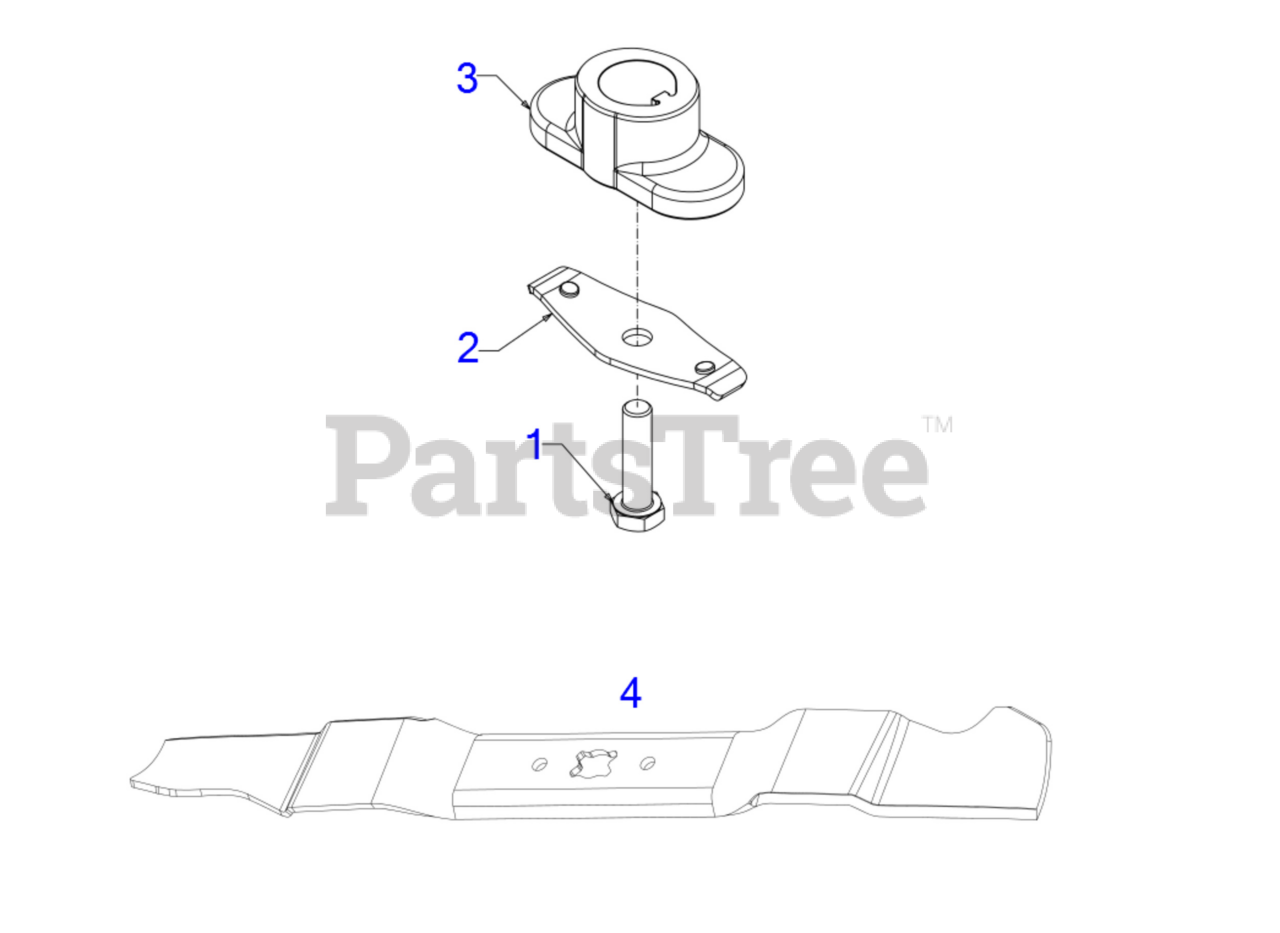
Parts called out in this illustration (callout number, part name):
1	SCREW 3/8-24 x 1.50 GR8
2	BLADE BELL SUPPORT
3	BLADE ADAPTER 25MM x 1.19
4	21" BLADE (MULCH)
